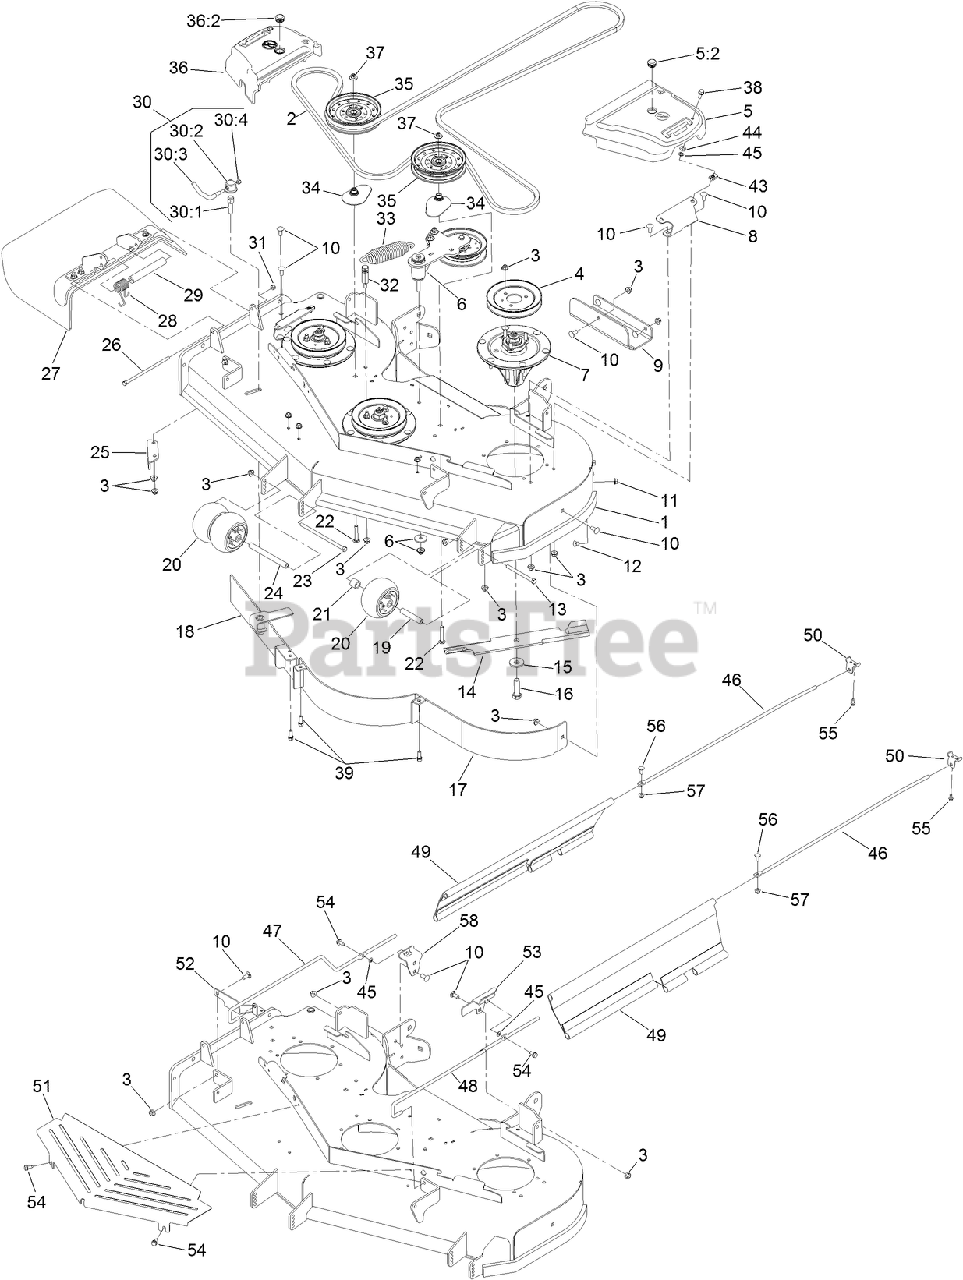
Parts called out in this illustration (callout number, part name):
1	DECK ASM
2	BELT-V
3	NUT-HF, NI
4	PULLEY
5	LH BELT COVER ASM
5:2	PLUG-PLASTIC
6	IDLER ARM ASM
7	SPINDLE ASM
8	BRACKET-COVER, BELT
9	PLATE-SKID
10	SCREW-CARR
11	NUT-HHF, WHIZ
12	SCREW-CARR
13	SCREW-HH
14	BLADE-18IN, HI FLOW
15	Washer-Blade Bolt, Heavy
16	SCREW-BLADE
17	BAFFLE ASM
18	ADJUSTABLE BAFFLE ASM
19	TUBE-SPANNER
20	ROLLER-SCALP, ANTI
21	TUBE-SPACER
22	BOLT-CARR, SHORT NECK
23	SCREW-HH
24	SPACER-WHEEL
25	BAFFLE-DISCHARGE
26	SCREW-HH
27	RUBBER DEFLECTOR ASM
28	SPRING-TORSION
29	SPACER
30	LEVER ASM
30:1	Screw-Lock
30:2	CAP-LOCK
30:3	Lever-Lock
30:4	NUT-LOCK, NI
31	NUT-LOCK, NI
32	ANCHOR-SPRING, TALL
33	SPRING-EXTENSION
34	SPACER-PULLEY
35	PULLEY-IDLER, FLAT
36	RH BELT COVER ASM
36:2	PLUG-PLASTIC
37	NUT-FLANGE, NI
38	SCREW-HHF
39	SCREW-HWH
43	NUT-U
44	WASHER-THRUST
45	NUT-PUSH
46	ROD-SUPPORT, UPPER
47	ROD-SUPPORT, LOWER (RH)
48	ROD-SUPPORT, LOWER (LH)
49	GUARD-SIDE
50	BRACKET-MOUNTING, UPPER
51	SHIELD-FRONT
52	BRACKET-MOUNTING, FRONT
53	BRACKET-MOUNTING, REAR (LH)
54	SCREW-HWHTF
55	SCREW-HWH
56	SCREW-CARR
57	NUT-HF, NI
58	BRACKET-MOUNTING, REAR (RH)
